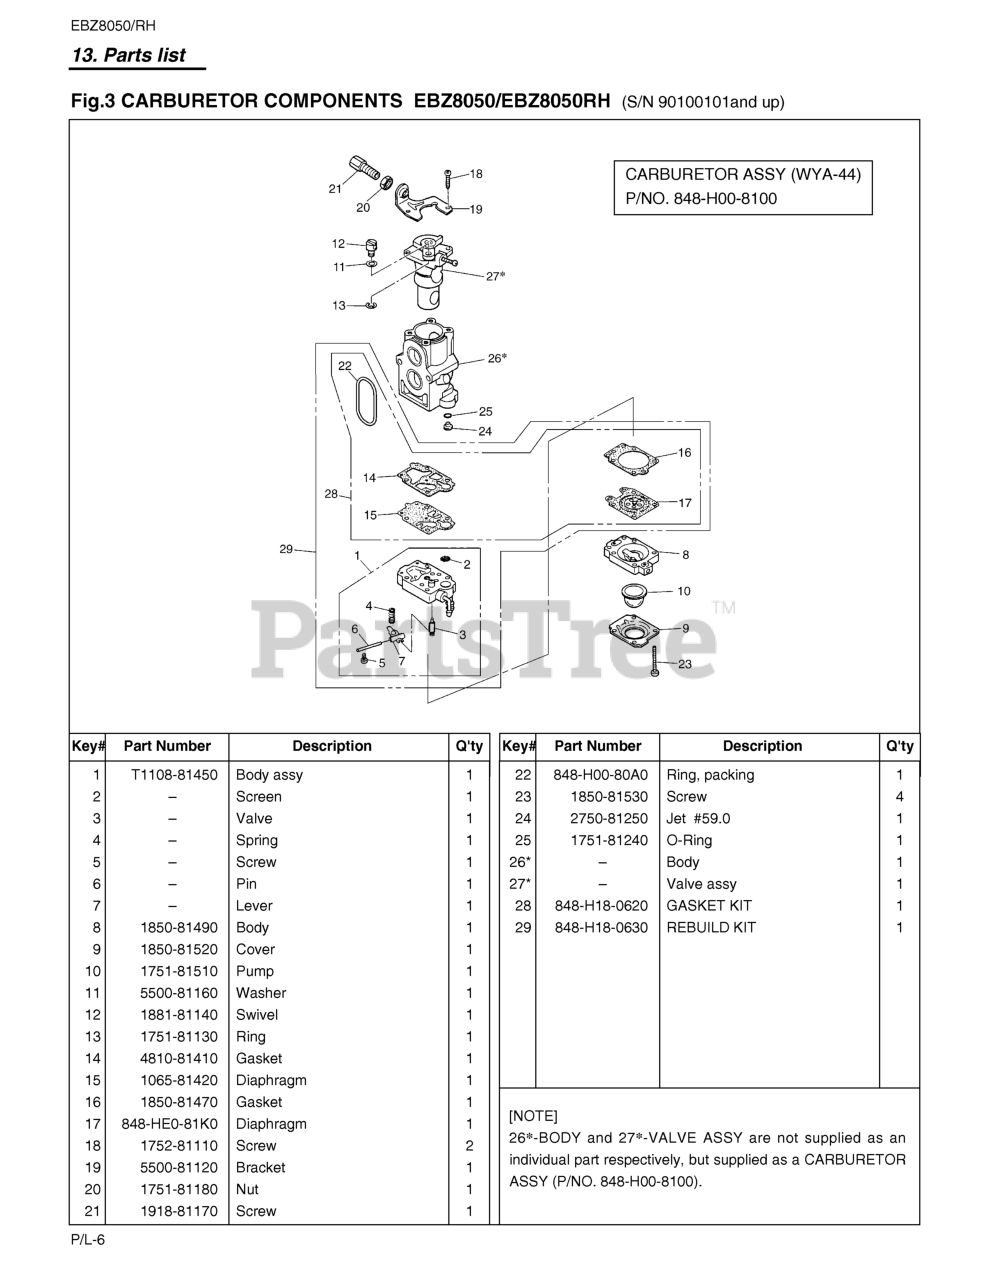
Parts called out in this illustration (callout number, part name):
1	BODY ASSY.
2	SCREEN
3	VALVE
4	SPRING
5	SCREW
6	PIN
7	LEVER
8	BODY
9	COVER
10	PUMP
11	WASHER
12	SWIVEL
13	RING
14	GASKET, PUMP
15	DIAPHRAGM
16	GASKET, DIAPHRAGM
17	DIAPHRAGM
18	SCREW
20	NUT
21	SCREW
22	RING, PACKING
23	SCREW
24	JET
25	O-RING
26	CARBURETOR-A (WYA-44)
27	CARBURETOR-A (WYA-44)
28	GASKET KIT
29	REBUILD KIT
